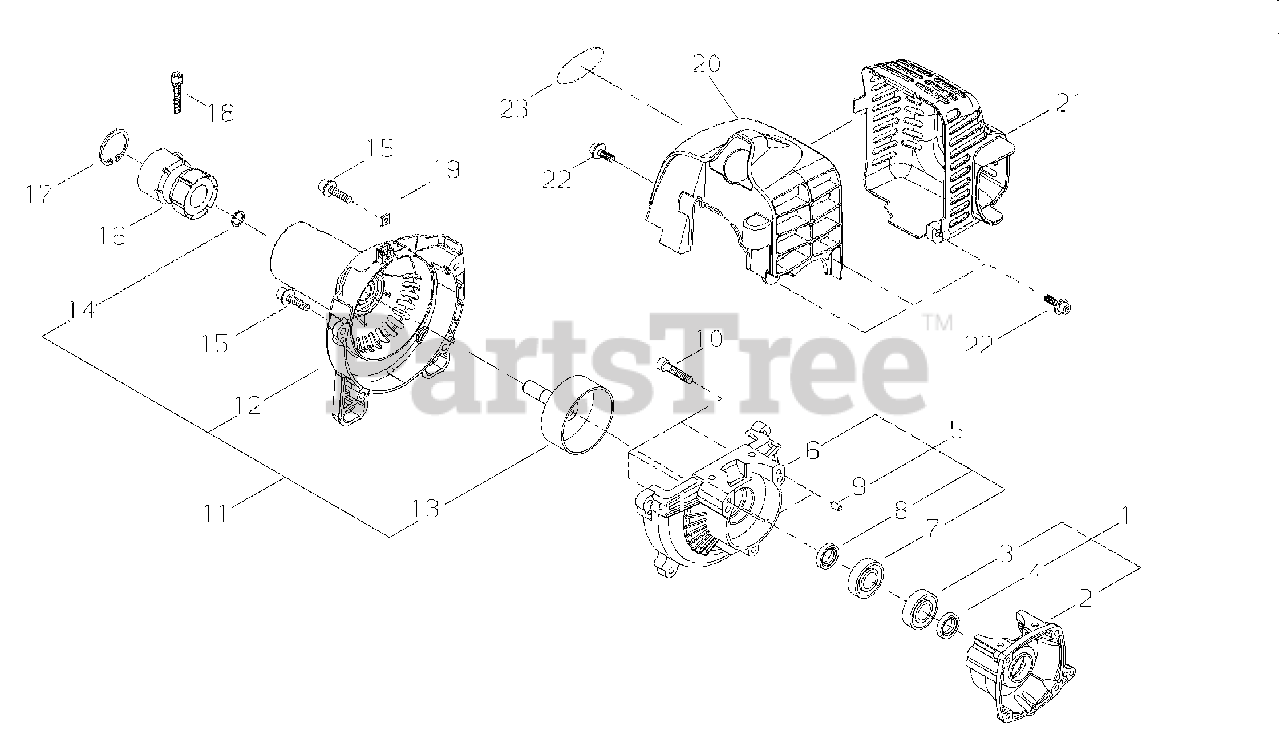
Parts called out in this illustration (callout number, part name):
1	CRANKCASE ASSY - REAR
2	CRANKCASE - REAR
3	BEARING, BALL - 6001C3
4	SEAL, OIL - 12
5	CRANKCASE ASSY - FRONT
6	CRANKCASE - FRONT
7	BEARING, BALL - 6001C3
8	SEAL, OIL - 12
9	PIN - LOCATING
10	SCREW - 5X25
11	FAN CASE ASSY
12	CASE, FAN
13	DRUM, CLUTCH
14	RING, RETAINING
15	SCREW - 5X18
16	CUSHION
17	RING, RETAINING - 40
18	SCREW - 5X22
19	NUT - 4
20	COVER, ENGINE
21	COVER, MUFFLER
22	SCREW - 4X16
23	LABEL - HOME PRO ID
